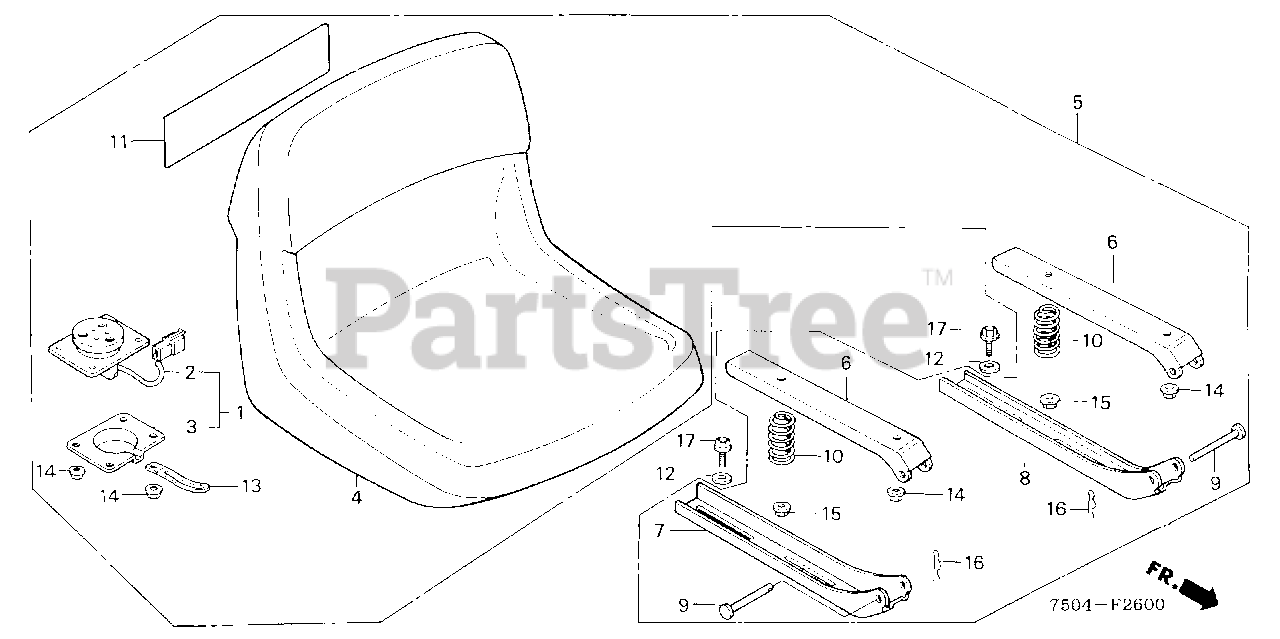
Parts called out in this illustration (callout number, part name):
2	SWITCH, SEAT
3	COVER, SEAT SWITCH
5	SEAT ASSY.
6	BASE, SEAT (UPPER)
7	BASE, R. SEAT (LOWER)
8	BASE, L. SEAT (LOWER)
9	PIN, SEAT BASE (8MM)
10	SPRING, SEAT
11	MARK, SEAT
12	WASHER, PLAIN (10MM)
13	CLIP, WIRE HARNESS
14	NUT, FLANGE (6MM)
15	NUT-WASHER (6MM)
16	PIN, LOCK (8MM)
17	BOLT, FLANGE (8X16)
